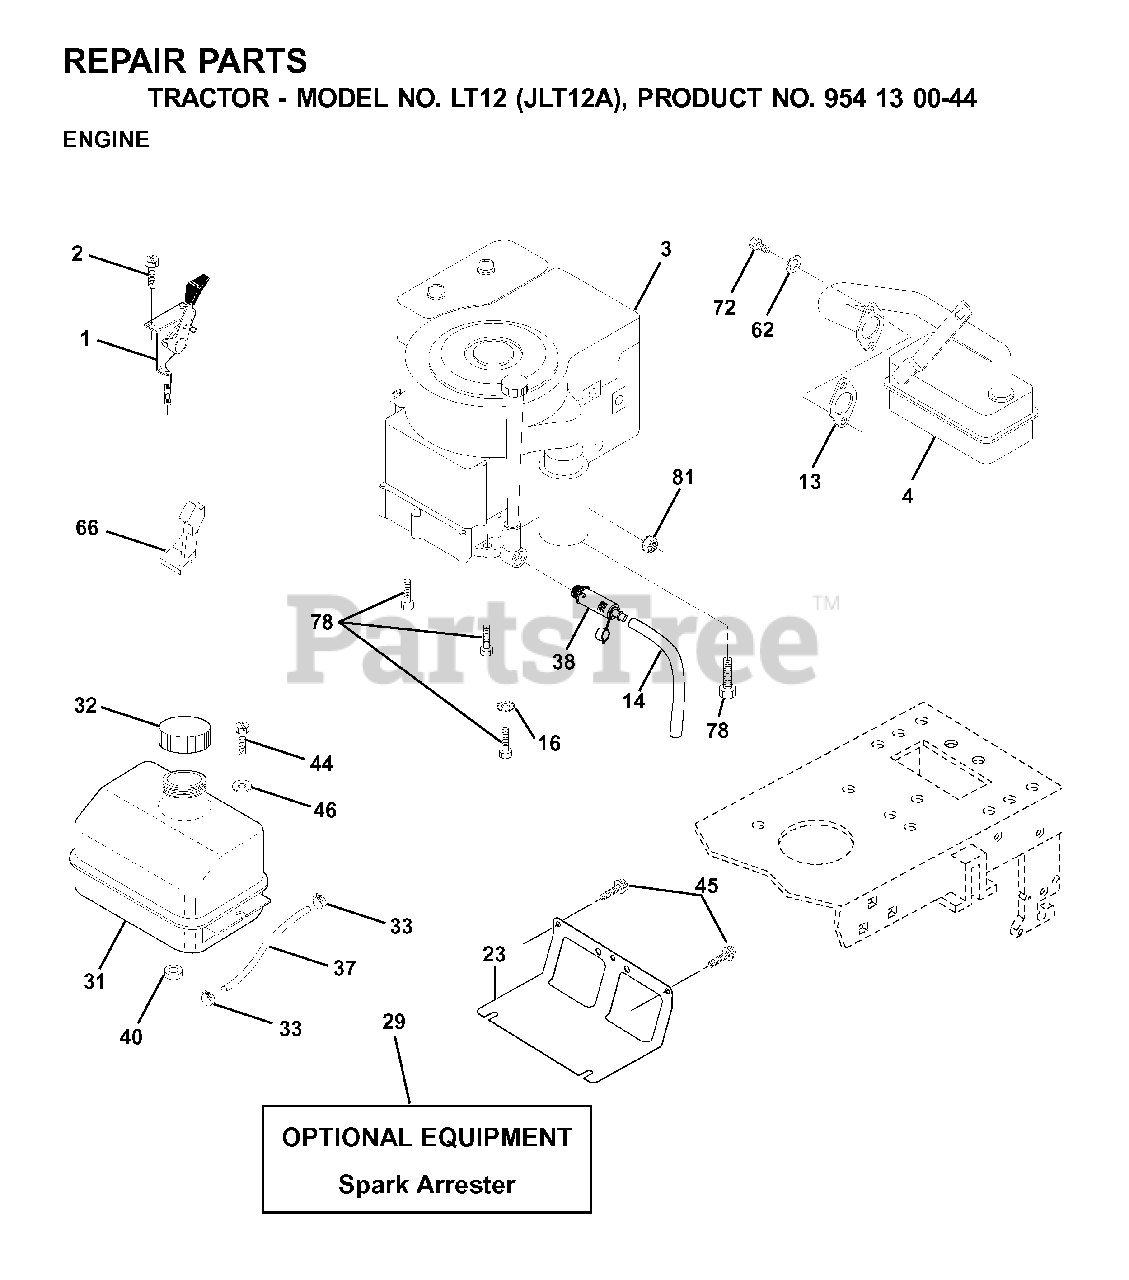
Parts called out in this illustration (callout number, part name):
1	THROTTLE CONTROL CABLE
2	SCREW LT
13	REPL BY 532 27 22-93
14	TUBE, DRAIN OIL ASM.
16	LOCKWASHER
23	SHEILD.BROWNING.DBR.GUARD
29	ARRESTER SPARK (OPTIONAL)
32	FUEL CAP
33	HOSE CLAMP
37	LINE.FUEL.20
38	PLUG, OIL DRAIN EASY
40	GROMMET T
44	SCREW HEXWSHR 1/4-20X3/4
45	SCREW, 3/8-16X3/4
46	WASHER
62	LOCKWASHER
66	STOP THROTTLE
72	SCREW
78	SCREW.3/8-16
81	NUT
